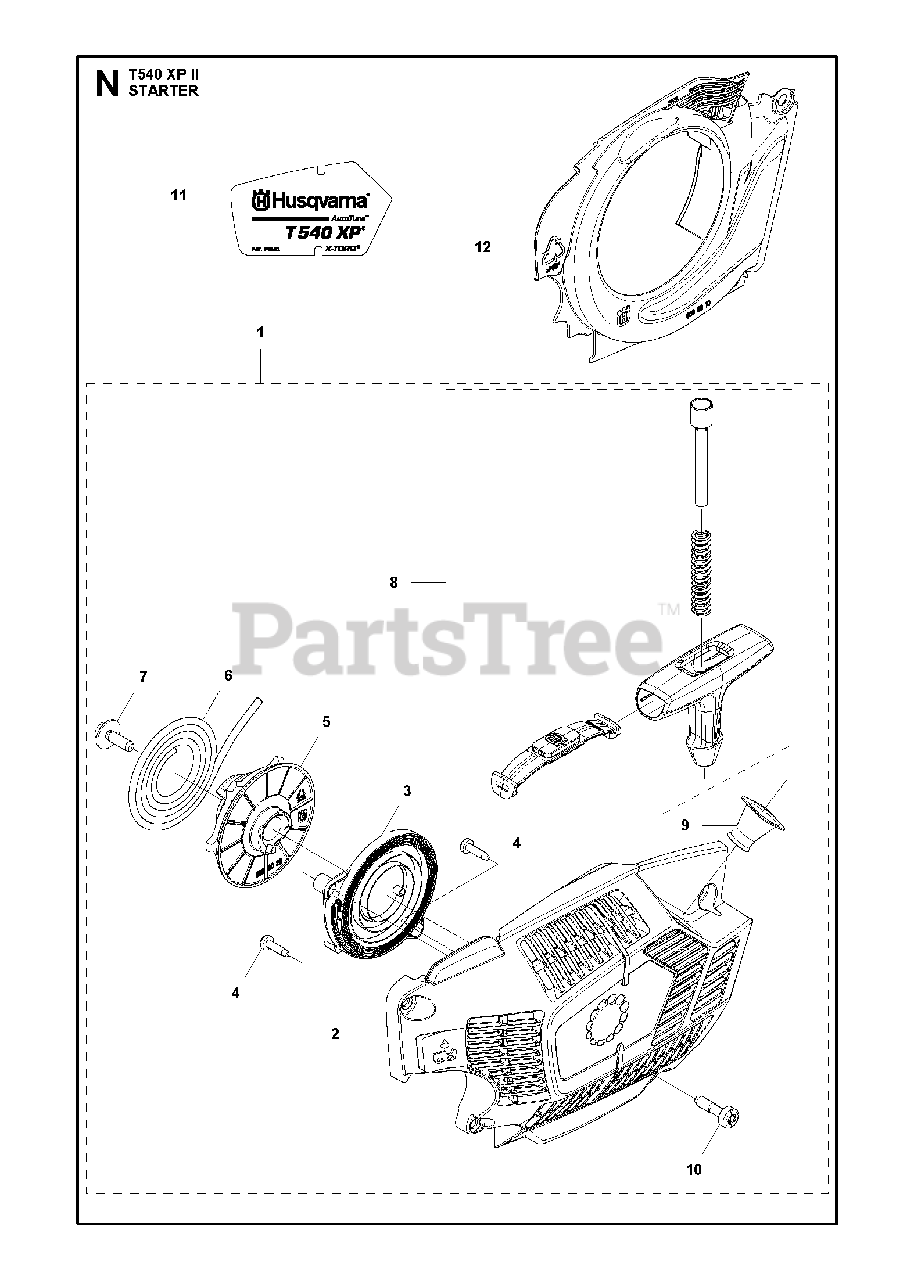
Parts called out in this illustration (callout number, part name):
1	STARTER ASSY
2	STARTER COVER
3	SPRING CASSETTE ASSY
4	SCREW CITXPANT
5	STARTER PULLEY
6	STARTER CORD
7	SCREW CITXSCT
8	STARTER HANDLE ASSY
9	SLEEVE
10	SCREW CITXPANMO
12	AIR CONDUCTOR
